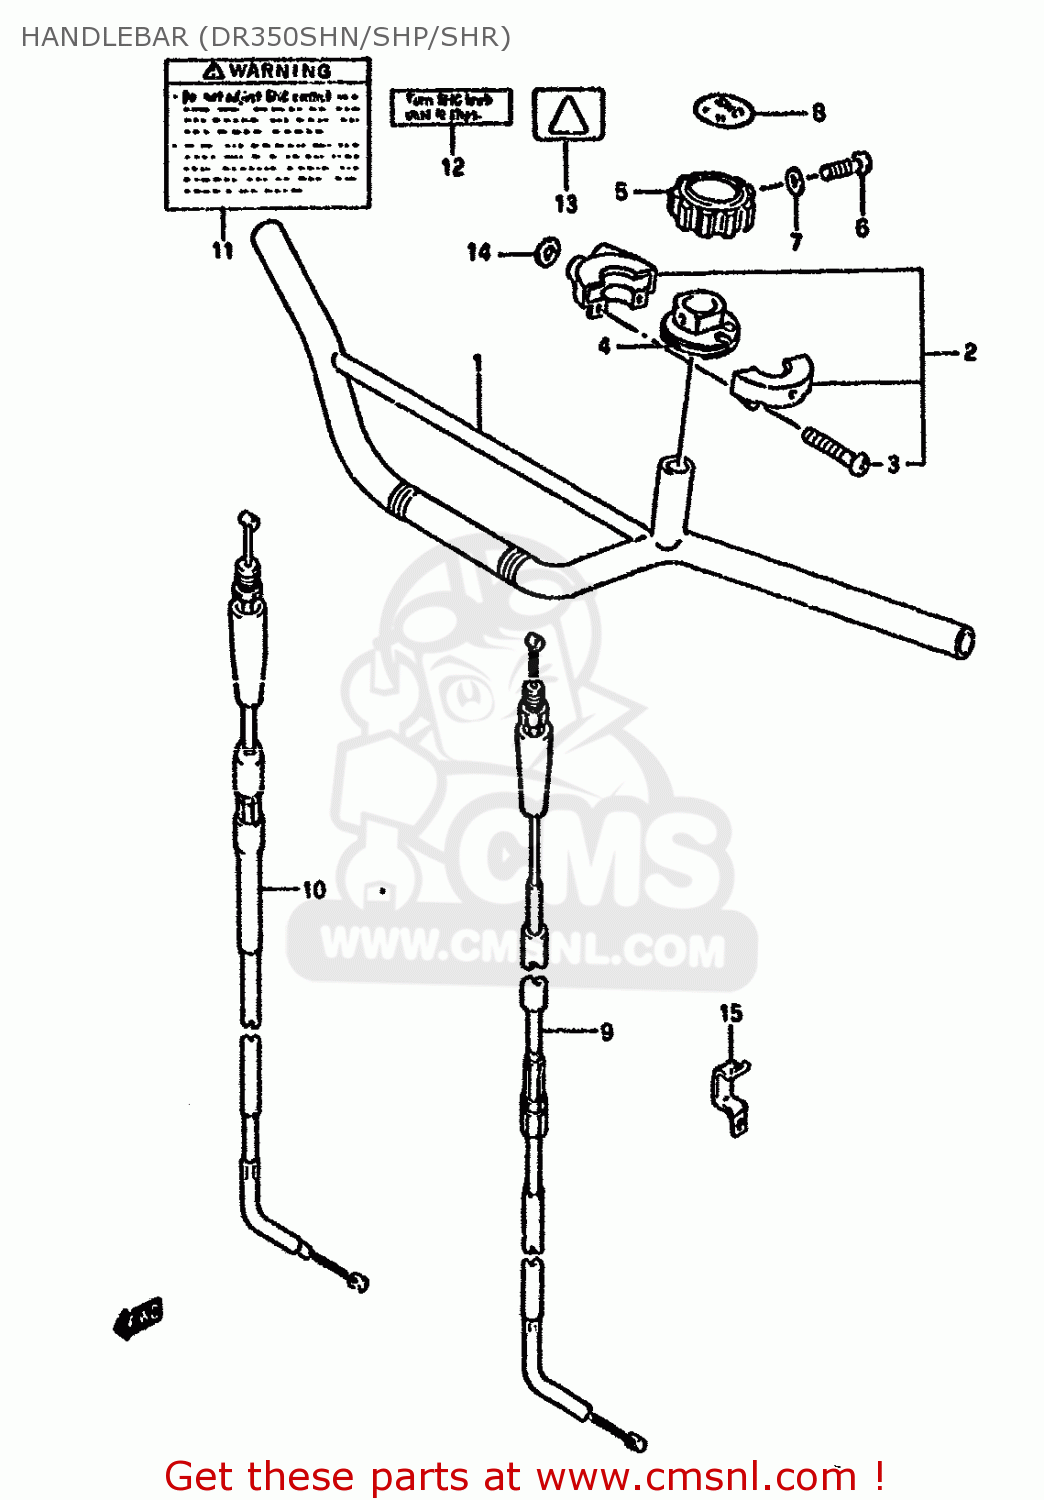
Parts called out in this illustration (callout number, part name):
1	HANDLEBAR
2	CASE ASSY,HIGH CONTROL
3	SCREW 5X20
4	ROTOR,HIGH CONTROL
5	KNOB,HIGH CONTROL
6	SCREW
7	WASHER,LOCK
8	EMBLEM,HIGH CONTROL
9	CABLE ASSY,HEI
10	CABLE ASSY,HEI
11	LABEL,WARNING HIGH CONTROL
12	LABEL,WARNING,KNOB SHC
13	LABEL,HIGH CONTROL
14	WASHER(10.5X19X2)
15	CLAMP
